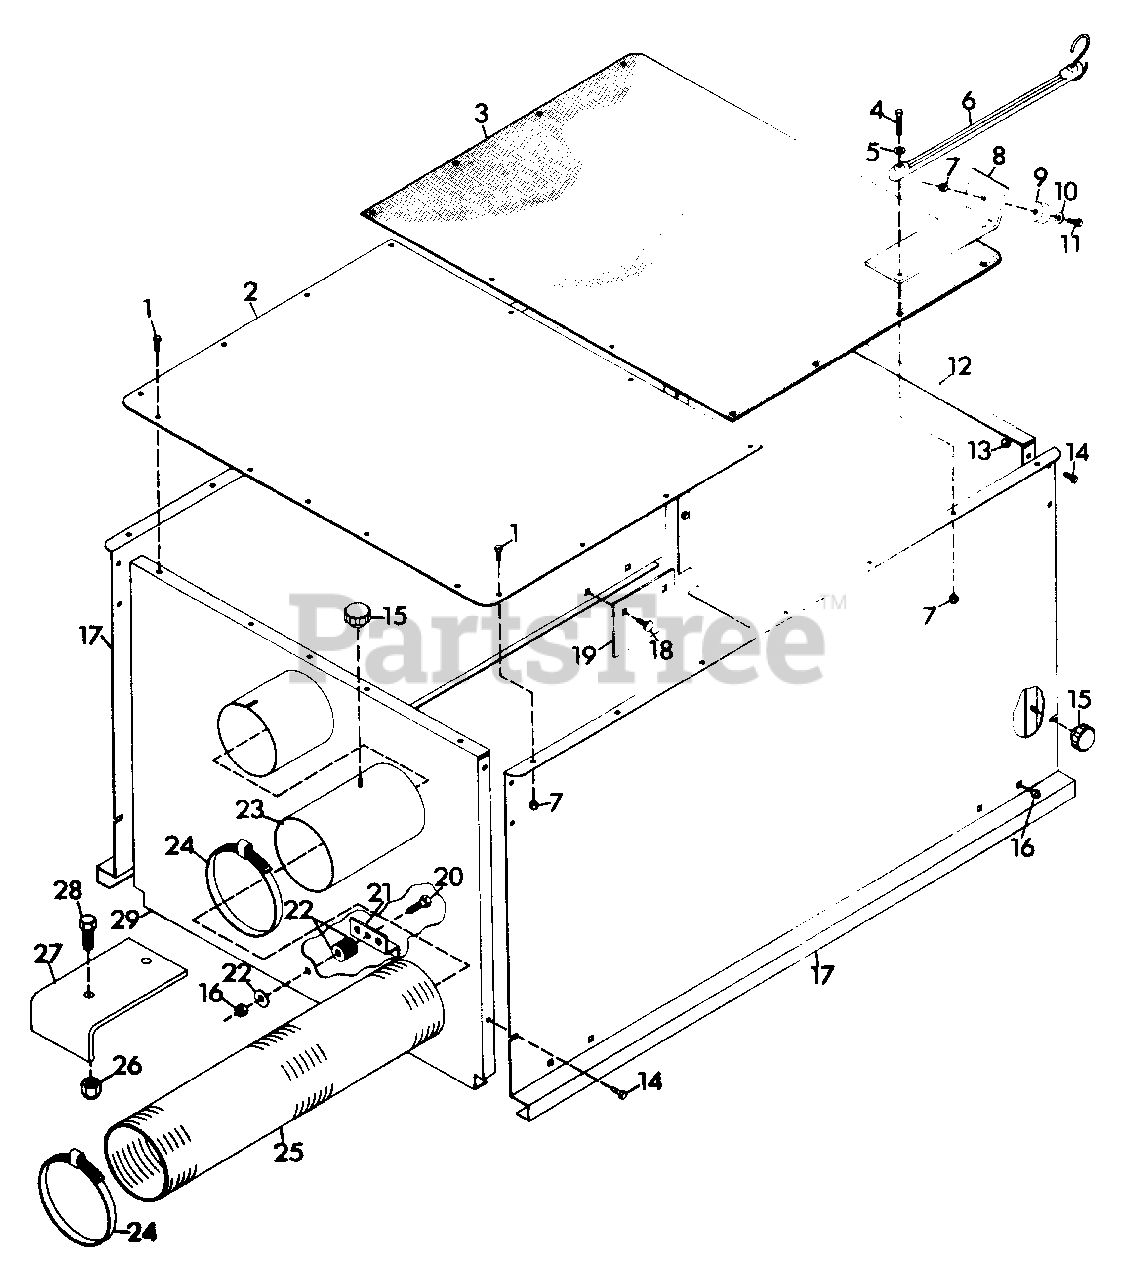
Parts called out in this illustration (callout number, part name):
1	BOLT, HEX 1/4-20X.75
2	COVER, TOP FRONT
3	COVER, TOP REAR
4	BOLT, HEX 1/4-20X1.375
5	WASHER, FLAT .281X.625X.065
6	STRAP, HOLD DOWN
7	NUT, LOCK 1/4-20
8	BRACKET
9	BUMPER, SEAT
10	WASHER, FLAT .312X.734X.065
11	BOLT, HEX 1/4-20X.875
12	WELDMENT, REAR GATE
13	NUT, LOCK 5/16-18
14	BOLT, HEX 5/16-18X.75
15	KNOB
16	NUT, LOCK 3/8-16
17	PANEL, SIDE
18	BOLT, CARRIAGE 3/8-16X.75
19	RETAINER, CART TOP
20	BOLT, HEX 3/8-16X1.25
21	BRACKET
22	WASHER, FLAT .375X1.125X.065
23	WELDMENT, CONNECTOR TUBE
24	CLAMP
25	HOSE, BLOWER TO CART
26	NUT, LOCK 5/8-11
27	EXTENSION, TONGUE
28	BOLT, HEX 5/8-11X1.50
29	GATE, FRONT WELDMENT
NS	DECAL, GRAVELY LOGO
